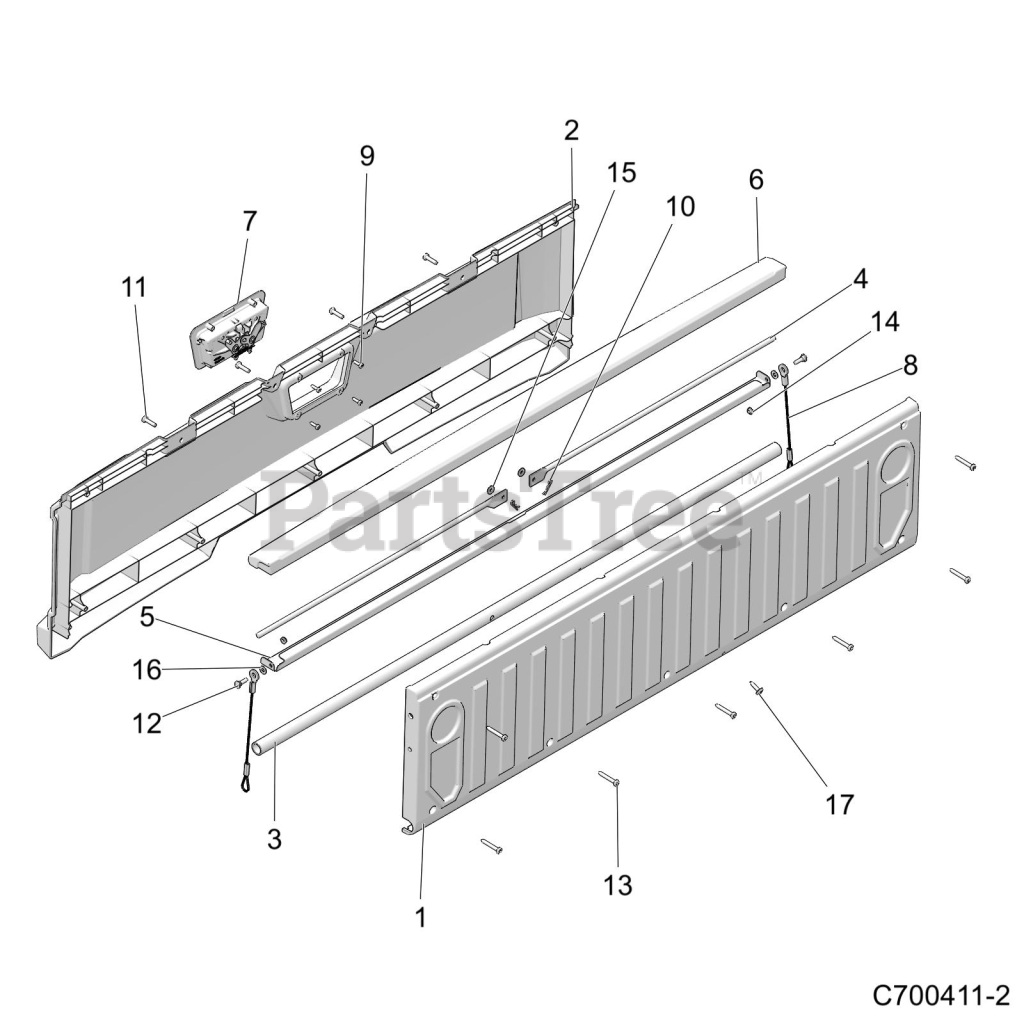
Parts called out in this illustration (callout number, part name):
1	PANEL, TAILGATE INNER BLACK
2	PANEL-TAILGATE,OUTER,BLK
3	TUBE-TAILGATE PIVOT,BLK
4	ROD, TAILGATE
5	BRACKET, TAILGATE
6	CAP, TAILGATE BLACK
7	LATCH, PADDLE
8	CABLE, TAILGATE
10	PIN, HITCH
11	SCR-#14X1 HI/LO-PH-PN TRX-M
12	BLT-SHLDR .188X.188X.25-20
14	NUT, HEX
16	WASHER, FLAT
